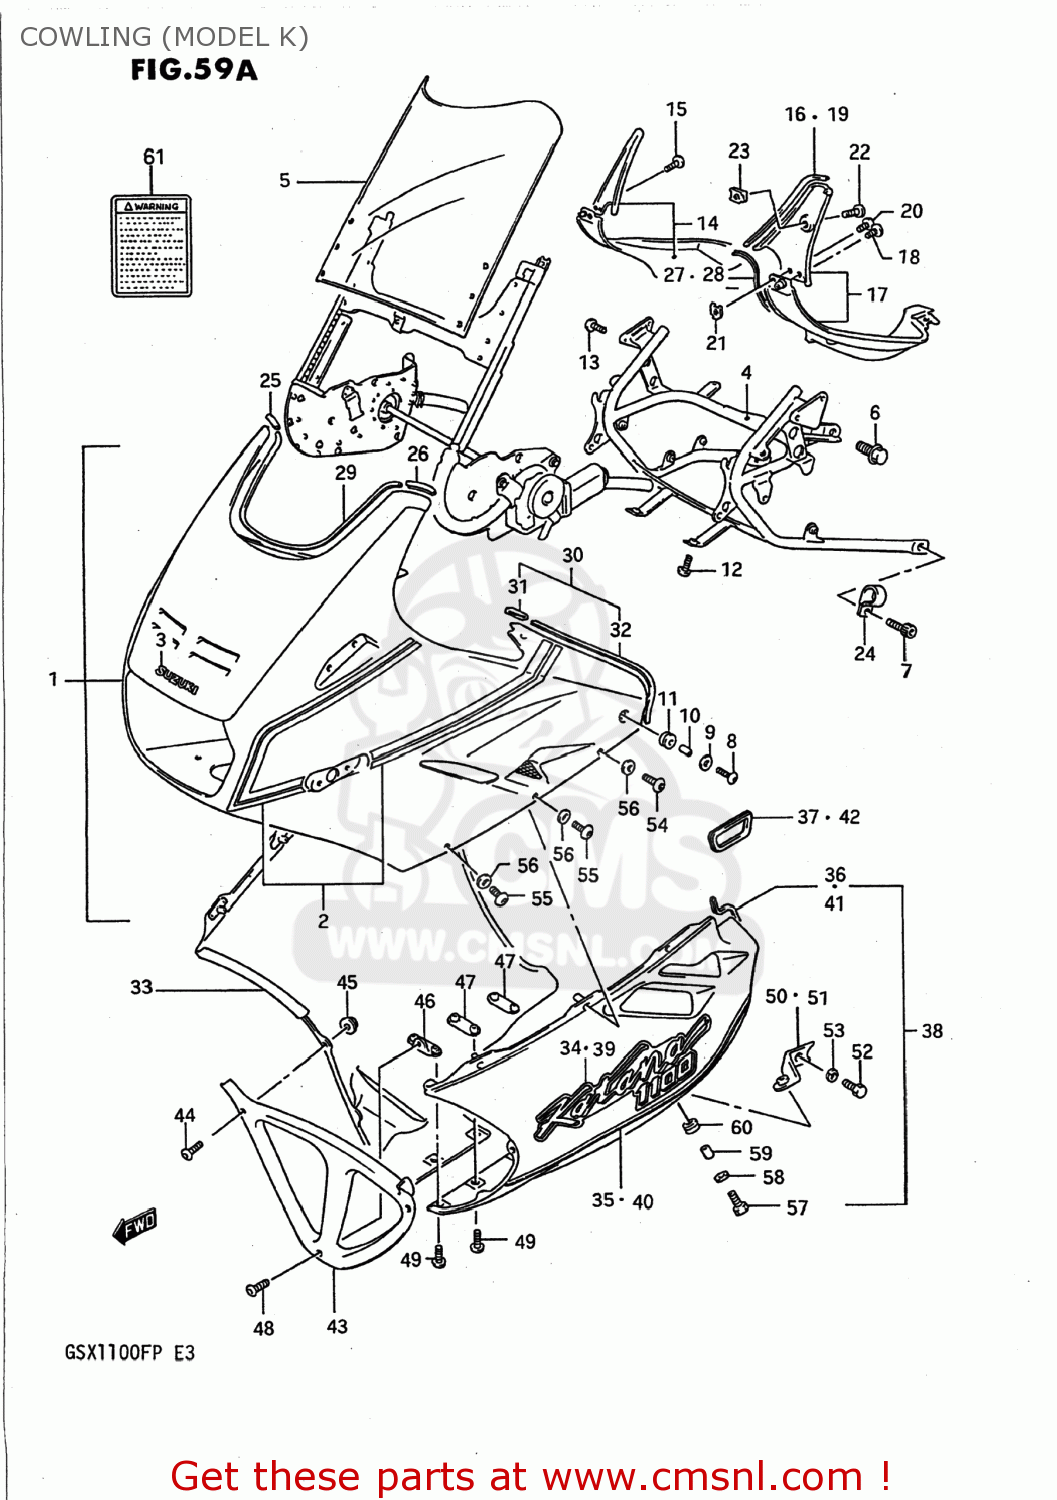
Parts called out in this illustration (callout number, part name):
1	BODY ASSEMBLY,COWLING
2	TAPE SET,COWLING
3	EMBLEM,COWLING,UPPER
4	BRACE,COWLING
5	WINDSCREEN
6	BOLT(10X12)
7	BOLT
8	SCREW(6X20)
9	WASHER(6.5X18X1)
10	SPACER
11	CUSHION
12	SCREW(6X16)
13	SCREW 6X12
14	PANEL ASSY,R
15	SCREW
16	MOLDING,COWL.
17	PANEL ASSY,L
18	SCREW
19	MOLDING,COWL.
20	SCREW, FRONT & REAR
21	NUT
22	SCREW
23	NUT
24	CLAMP
25	CAP,PANEL & COWLING,R
26	CAP,PANEL & COWLING,L
27	MOLDING,COWLING PANEL,R
28	MOLDING,COWLING PANEL
29	MOULDING
30	MOLDING,COWLING BODY SIDE
31	COVER,MOLDING END
32	MOLDING,COWLING BODY SIDE
33	COVER ASSEMBLY,COWLING,LOWER
34	EMBLEM
35	TAPE,COWLING,RIGHT
36	MOLDING,COWLING,LOWER
37	MOLDING,INLET
38	COVER ASSEMBLY,COWLING,LOWER
39	EMBLEM
40	TAPE,COWLING
41	MOLDING,COWLING,LOWER
42	MOLDING,INLET
43	COVER,COWLING,LOWER,FRONT
44	SCREW(5X14)
45	NUT
46	BRACE,COWLING LWR COVER
47	BRACE,COWLING LWR COVER RR
48	SCREW(6X12)
49	SCREW(6X16)
50	BRACE,COWLING LWR,R
51	BRACE,COWLING LWR,L
52	BOLT 8X12
53	LOCK WASHER
54	SCREW(6X20)
55	SCREW(6X16)
56	WASHER
57	SCREW(6X20)
58	WASHER(6.5X18X1)
59	SPACER(6.4X9.2X12)
60	CUSHION
61	LABEL (WARNING SCREEN)
